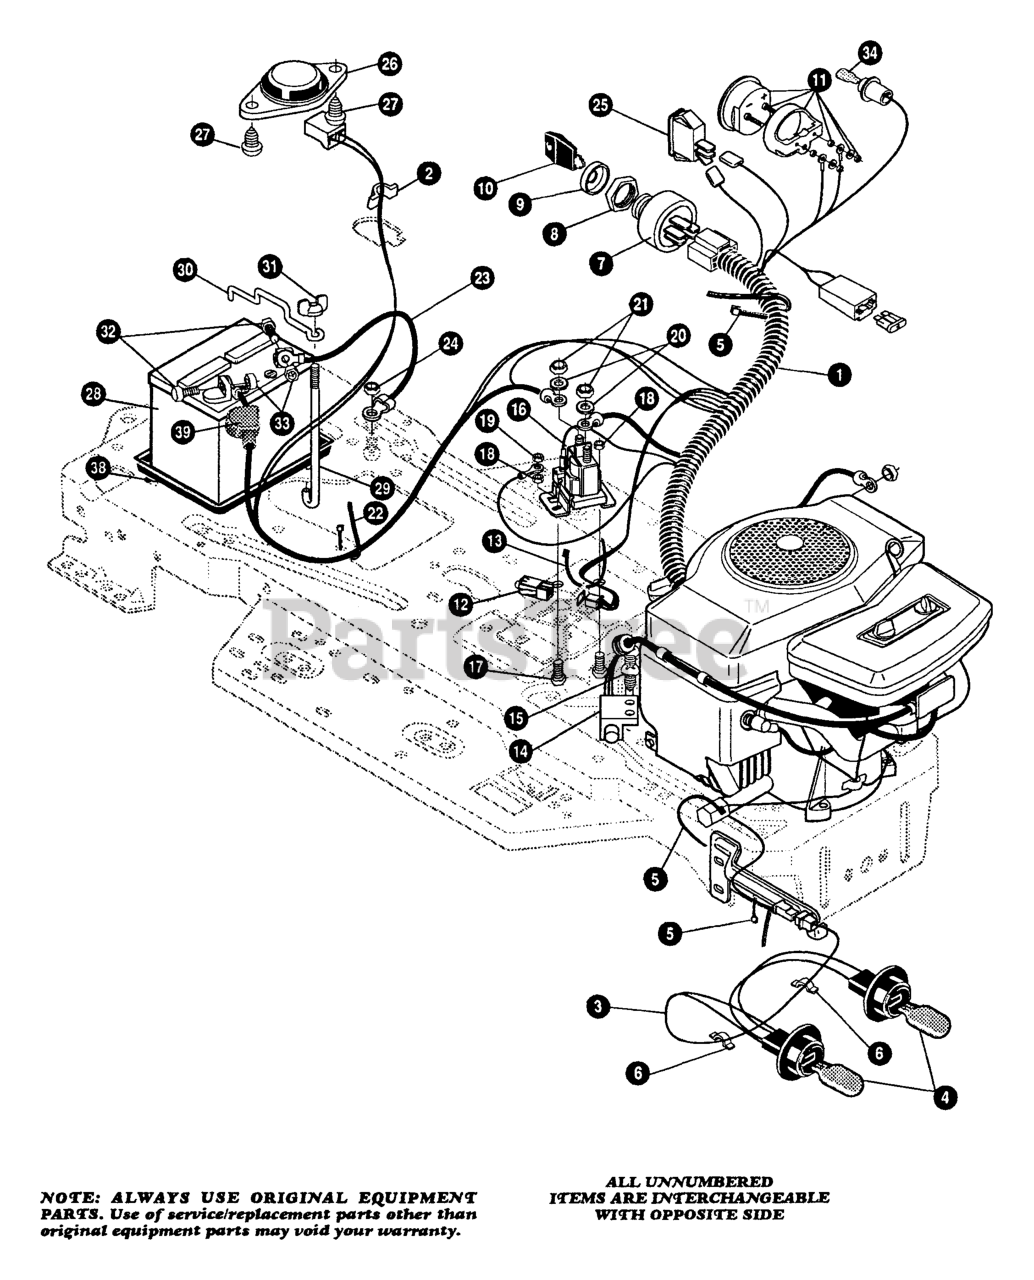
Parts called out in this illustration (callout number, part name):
1	HARNESS, WIRE
2	PRESS CLIP
3	ASSY, LIGHT WIRE
4	BULB, HEADLAMP
5	TIE, CABLE
6	PRESS CLIP
7	SWITCH-IGNITION
9	BOOT, IGN SWITCH
10	KEY, IGNITION
11	AMMETER ASSY
13	TIE, CABLE
15	SCREW
16	SOLENOID
17	SCREW
22	TIE, CABLE
23	WIRE, GROUND
25	LIGHT SWITCH
26	SWITCH, SEAT
28	BATTERY
29	ROD, BATTERY
30	ROD, BATTERY, TOP
31	NUT, WING
34	BULB, INDICATOR
38	TRAY - BATTERY
39	BOOT, BATTERY
